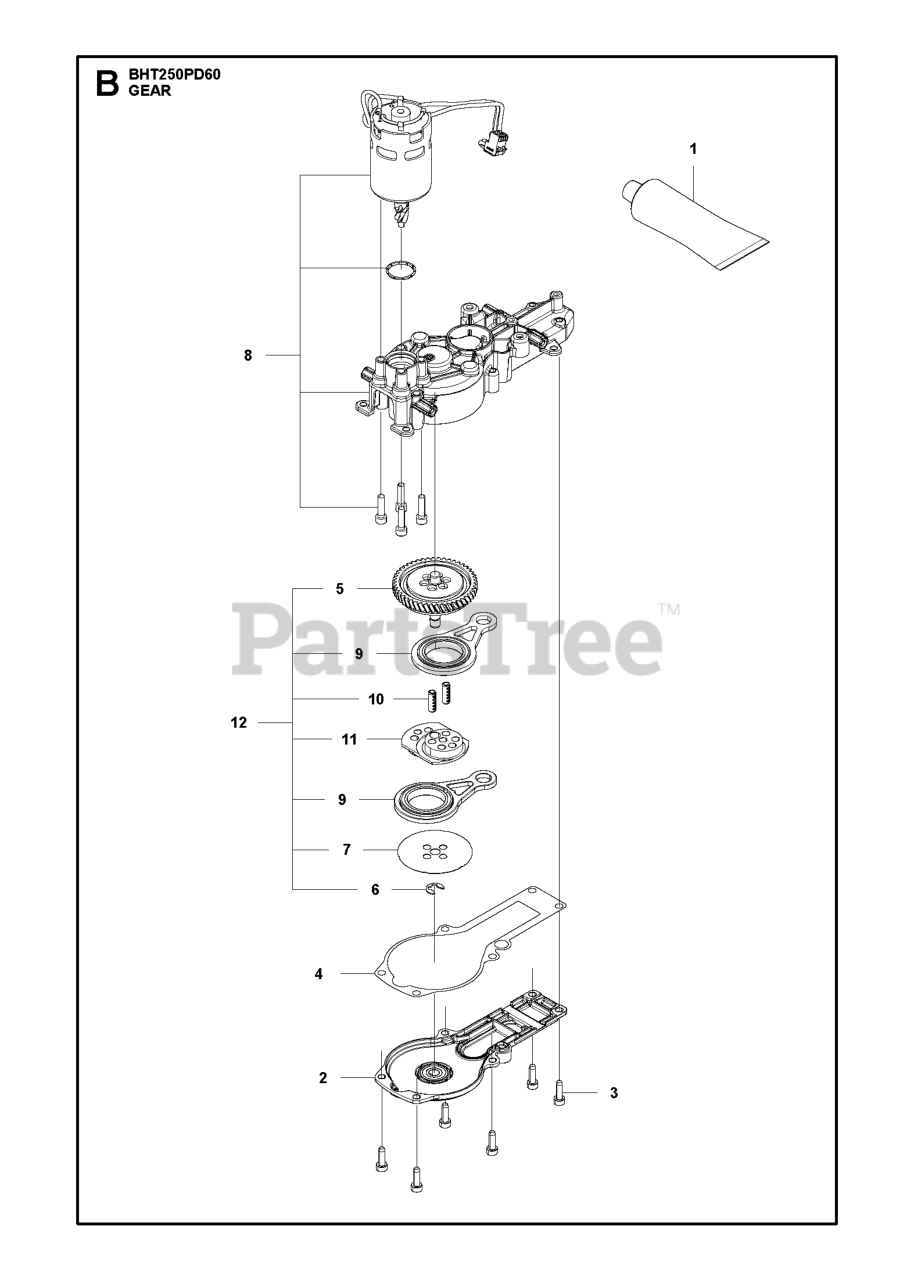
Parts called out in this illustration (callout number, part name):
1	GREASE 20G HEDGE TRIMMER GEAR
2	BASEPLATE ASSEMBLY UNBRANDED
3	SCREW IHSCFT
5	HELICAL GEAR CPL DC
6	LOCK WASHER
7	WASHER DISK DISC
8	MOTOR ASSY MOTOR-GEARBOX ASSY
9	CONNECTING ROD ASSY
10	HEAVY DUTY DOWEL PIN PROJEKT 1
11	ECCENTRIC DISC
12	GEAR HELICAL KIT 536LIHD60X/ 5
